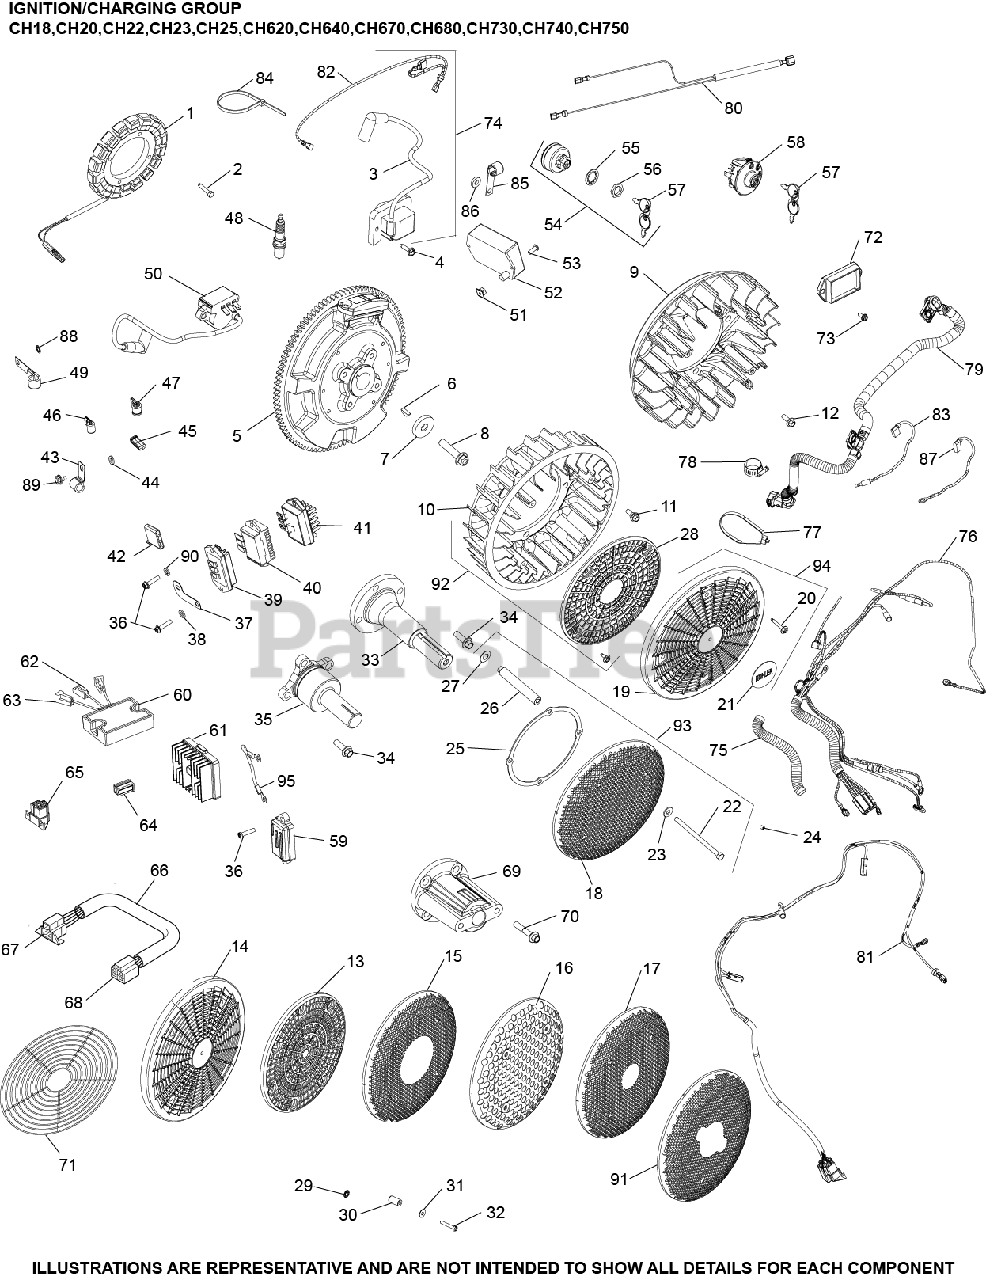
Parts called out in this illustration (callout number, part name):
1	KIT, 15 / 20 AMP STATOR
2	SCREW, M5X0.8X25 - (#25086402S)
3	MODULE, MAGNETO DIGITAL IGNITION USE 25 584 14-S
4	SCREW, FLG THD FRM M5X.8X20-(#25086399S)
5	FLYWHEEL ASSEMBLY (LW)
6	KEY, 3/16" X 5/8"
7	WASHER, FLAT 13/32"
8	SCREW, FLG M10X1.5X45 - (#25086361S)
9	FAN USE 24 755 253-S
11	BOLT, SHOULDER
19	KIT, GRASS SCREEN
20	SCREW, FLG SEMS M4X.7X25
36	SCREW, HEX FLANGE HI-LO
37	BRACKET, GROUND STRAP USE 24 518 12-S
40	REGULATOR, RECTIFIER USE 25 403 29-S
42	CONNECTOR
43	CLIP, CABLE
44	WASHER, FLAT 1/4" (O.D. 1/2")
48	PLUG, SPARK (PRO SERIES)
50	MODULE, SPARK ADV (DSAI)-USE 24 584 89-S
57	KEY, SET OF 2
58	KIT, KEY SWITCH (SNAP-IN)
76	HARNESS, WIRING ASSEMBLY
82	LEAD, DUPLEX
83	LEAD, OIL SENTRY
87	LEAD, 20/25 AMP B+
90	WASHER, LOCK
